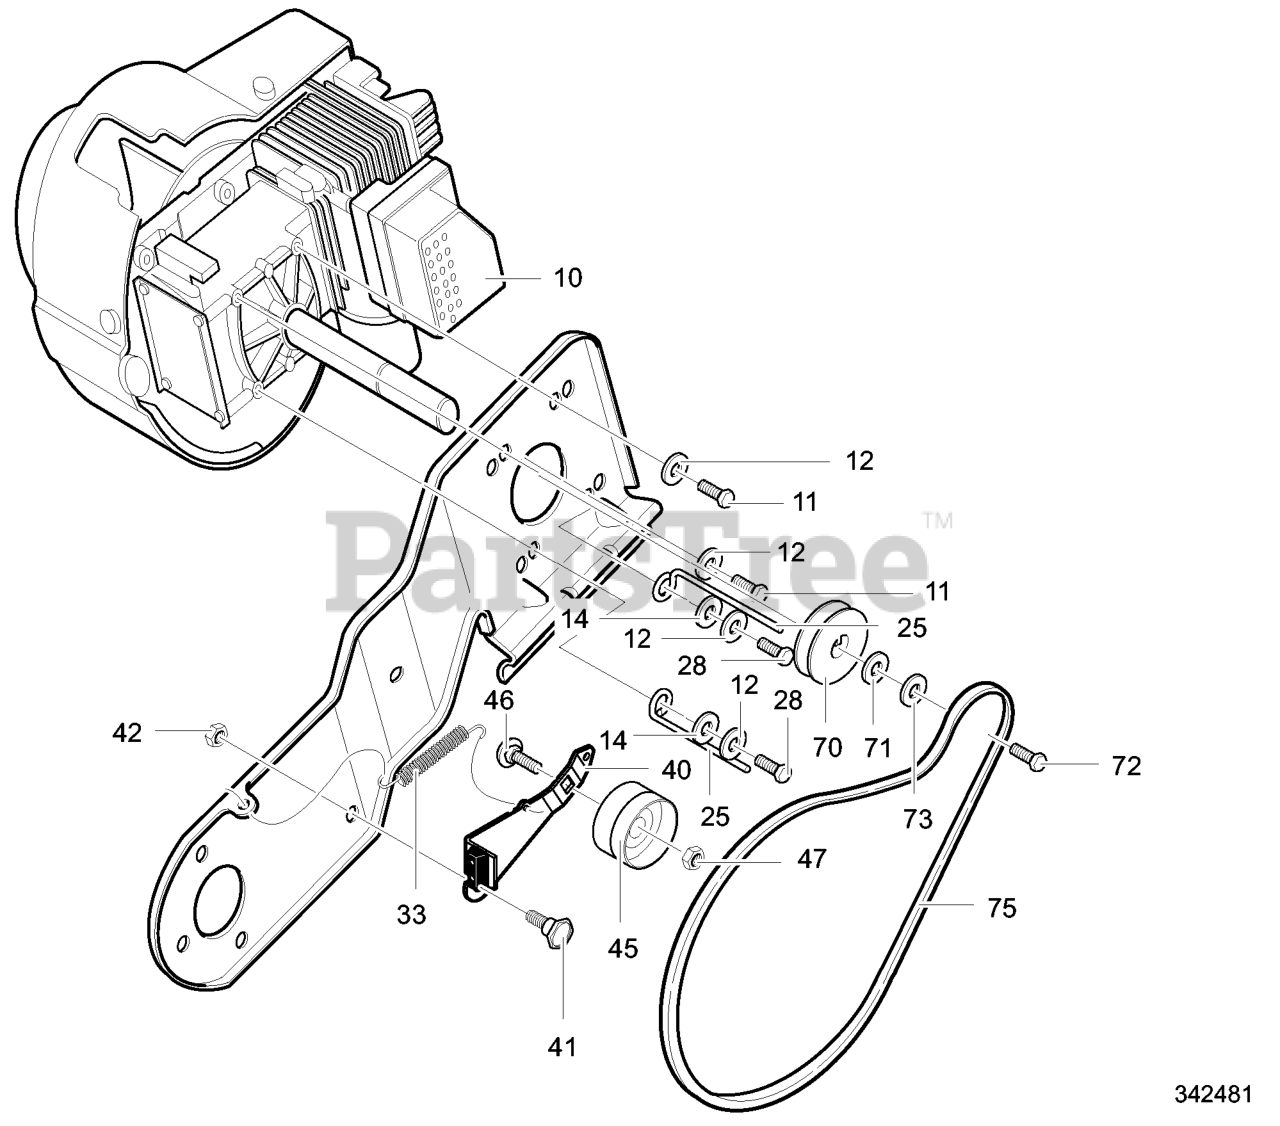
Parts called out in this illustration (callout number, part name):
10	ENGINE
11	SCREW, 5/16-18 x 0.75
12	WASHER, SPTLK
14	FLATWASHER
25	BELT GUIDE
28	SCREW, 5/16-18 x 1.00
33	SPRING, IDLER BRAKE
40	IDLER BRAKE ARM
42	NUT
45	PULLEY, IDLER
47	NUT
71	WASHER
72	SCREW, 5/16-24 x .75
73	WASHER
75	BELT, V 3L 34.8"
